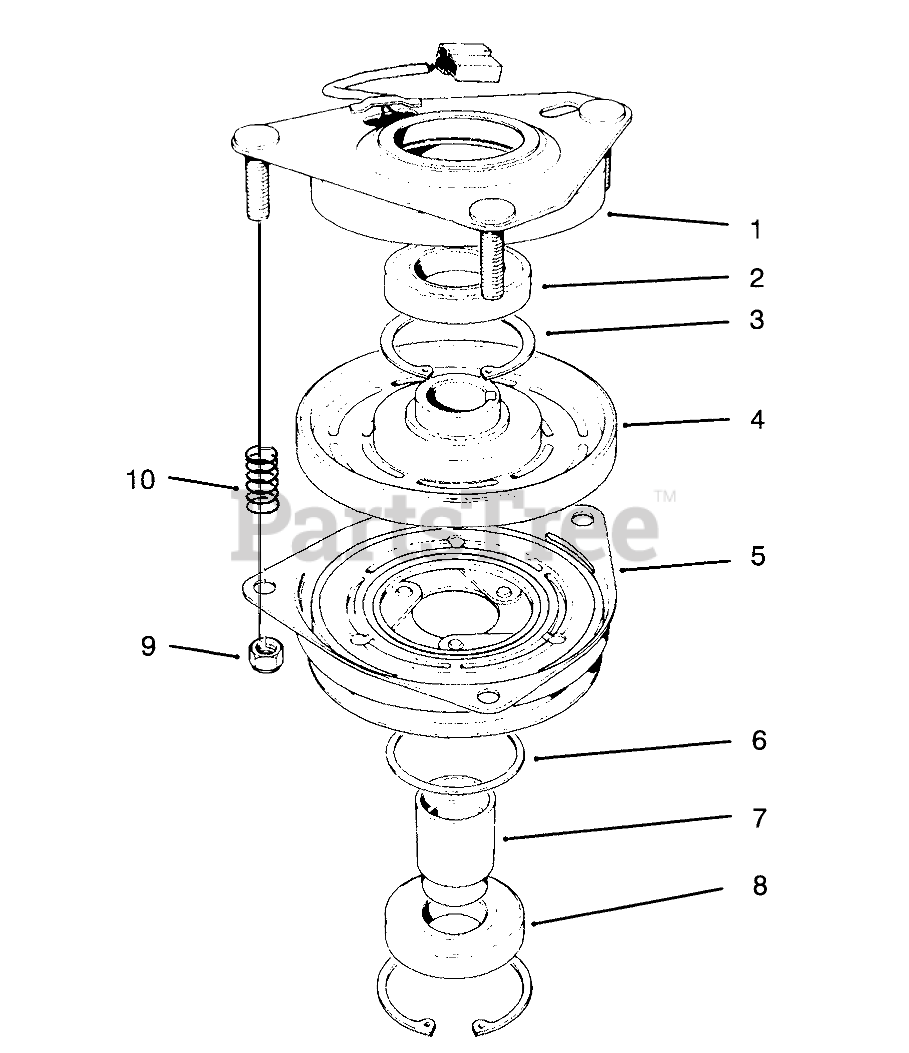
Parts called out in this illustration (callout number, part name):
1	Field Ass-y (Incl. Ref. #2 & 3)
2	BEARING-FIELD
3	RING-RETAINING
4	Field Coil, Rotor & Bearing Assembly (Incl. Ref. #1)
5	Armature & Pulley Assemble (Incl. Ref. #3, 6, 7, & 8)
6	SPACER-BEARING, PULLEY
7	COLLAR-BEARING
8	BEARING-PULLEY
9	NUT-HEX
10	SPRING
